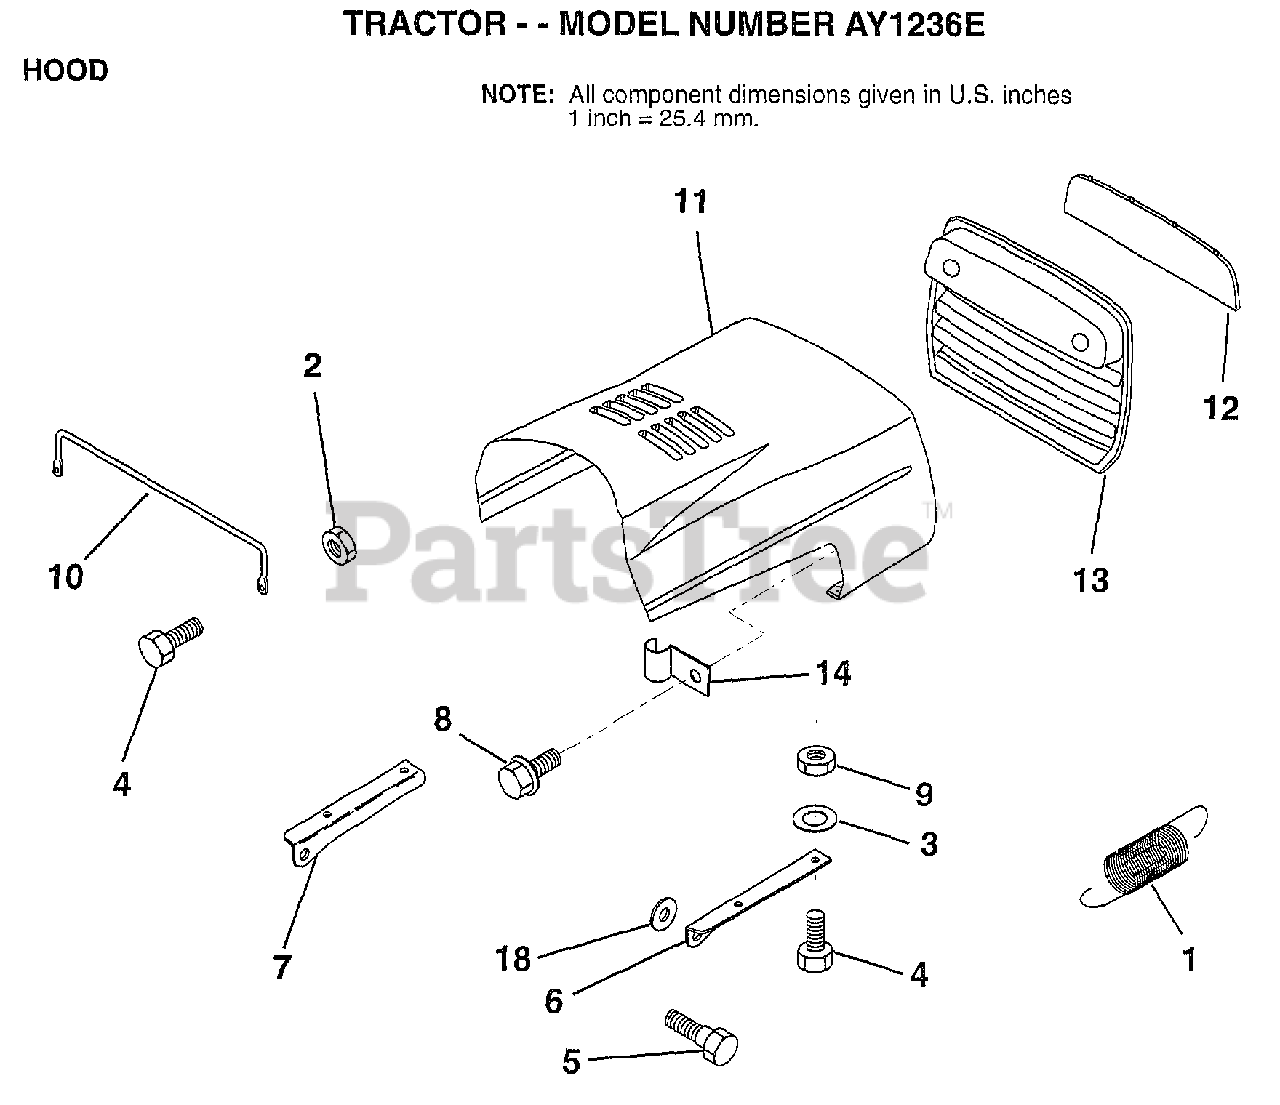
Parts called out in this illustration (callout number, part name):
1	EXT SPRING
2	NUT
3	WASHER
5	BOLT.SHLD.5/16-18
6	BRKT HOOD RH
7	BRKT HOOD LH
8	"SCREW,HWHD.HI-LO#13-16X3/4"
9	NUT
10	"BRACE,HOOD"
11	HOOD.IMPREG.MS550
12	LENS
13	GRILL
18	WASHER
